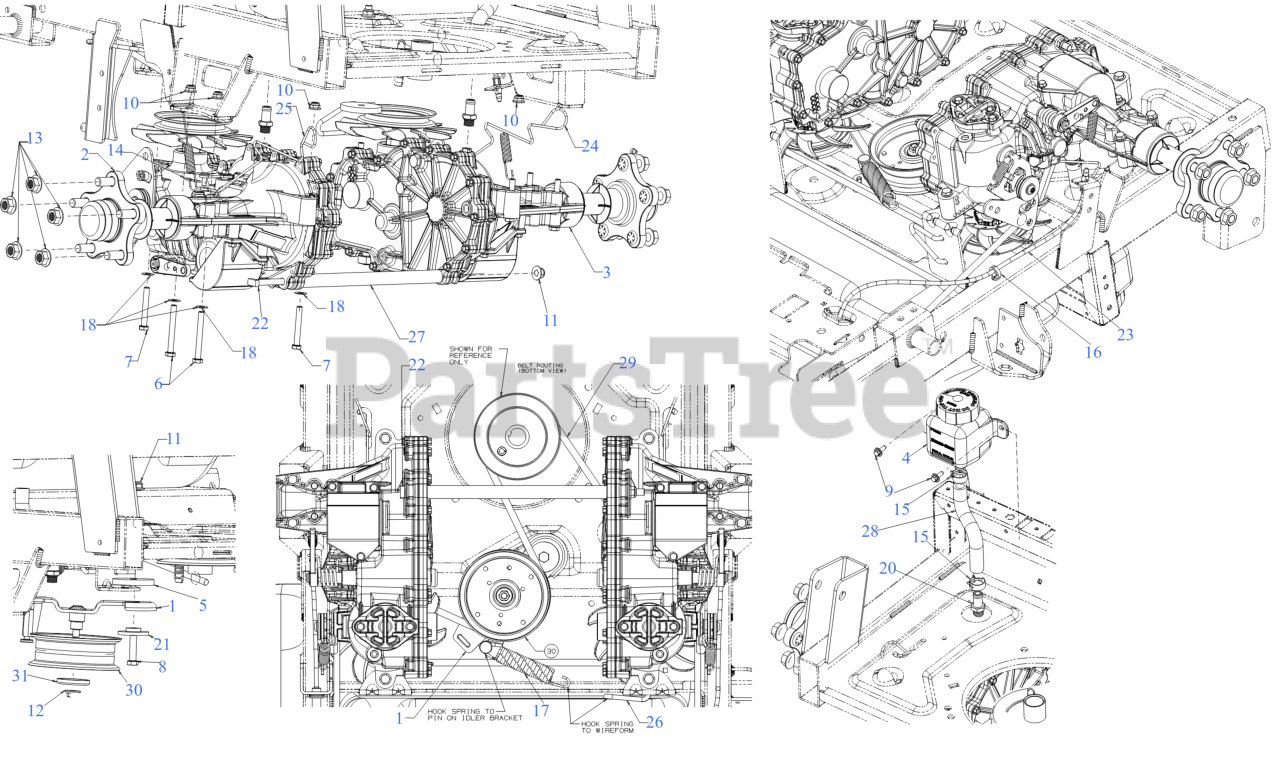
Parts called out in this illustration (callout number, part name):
1	DRIVE IDLER BRACKET
2	HYDRO TRANSMISSION (LH)
3	HYDRO TRANSMISSION (RH)
4	EXPANSION TANK
4	CAP-EXPANSION TANK
5	SPACER PLATE
6	HEX SCREW 5/16-18 x 2.75
7	HEX SCREW 5/16-18 x 2.25 GR5
8	SCREW 3/8-16 x 1.50
9	SCREW M6-1 x .625
10	FLANGE LOCK NUT 5/16-18
12	FLANGE LOCK NUT
13	HEX FLANGE NUT 1/2-20 GR8
14	BOW TIE COTTER PIN 1/4-5/16
15	FUEL HOSE CLAMP .75
16	CABLE RETAINER CLIP
17	EXTENSION SPRING .925 x 5.37
18	FLAT WASHER
20	BARB FITTING 9/16-18
21	SHOULDER SPACER
22	SUPPORT TUBE ROD
23	PARK BRAKE CABLE
24	HYDRO BYPASS ROD (RH)
25	HYDRO BYPASS ROD (LH)
26	IDLER SPRING HOOK
27	SUPPORT TUBE
28	EXPANSION TANK HOSE
29	TRANSMISSION DRIVE BELT A x 67
30	IDLER PULLEY 4.50" DIA
31	IDLER PULLEY CAP
